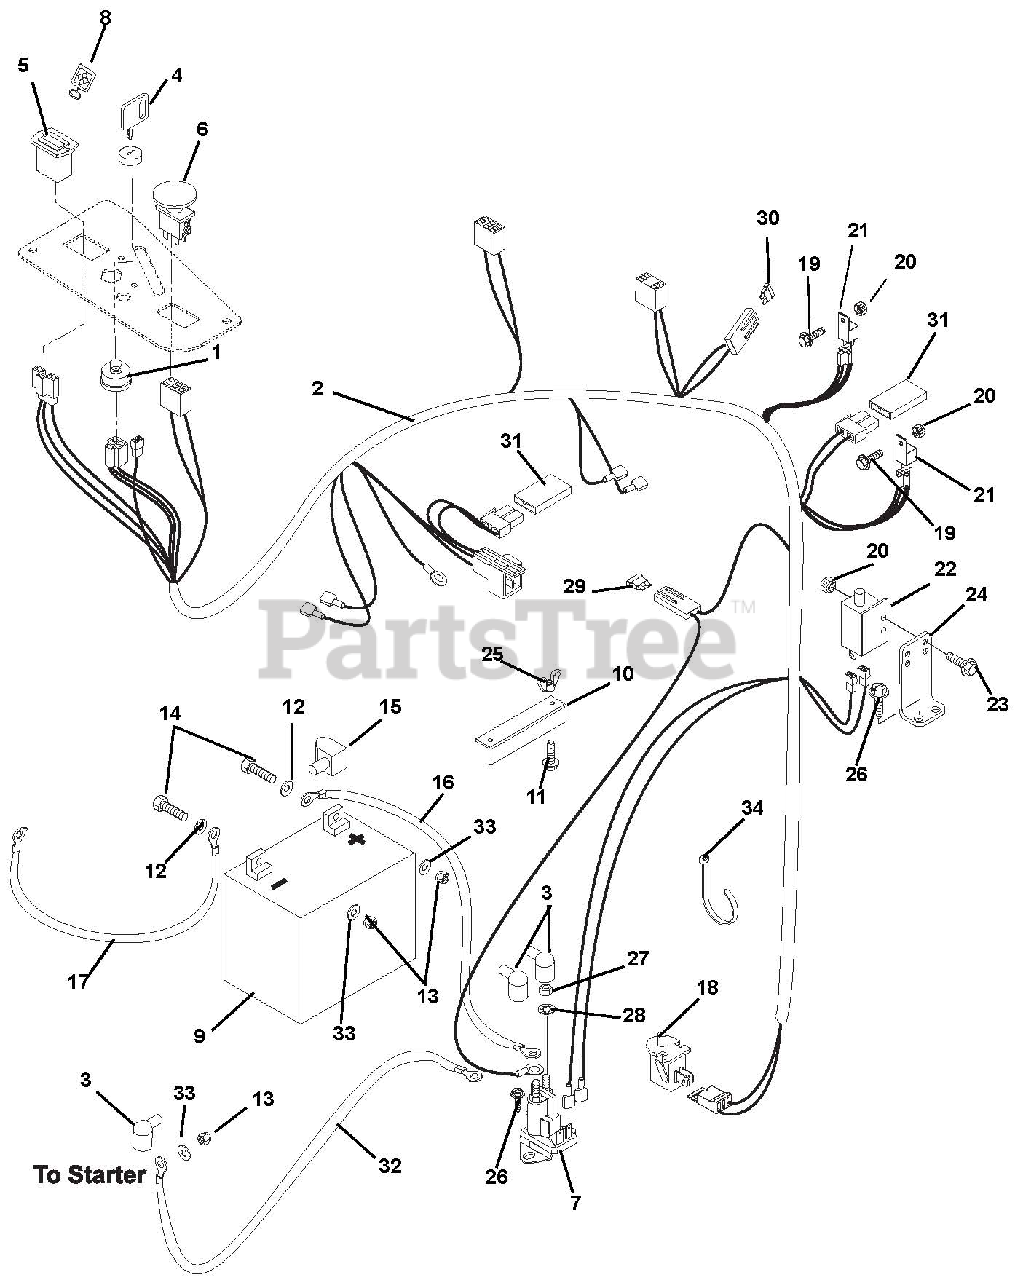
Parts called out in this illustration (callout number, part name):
1	Key Switch
2	Harness, Wiring IZ/CZ 6-Pin
3	Boot, Eyelet Terminal
4	Key with Shield
5	Hour Meter – Digital
6	Switch, Clutch With Retainer Ring
7	Solenoid
8	Key Chain
10	Hold Down
11	Bolt, Round Head Square Neck .25-20 x 7.50
12	Washer, Flat Steel .281 x .620 x .065
13	Nut, Hex .25-20
14	Bolt, Hex .25-20 x .75 Grade 5
15	Insulator
16	Cable, Positive Battery 9.00"
17	Cable, Negative Battery
18	Switch, Snap Mounting (N.O.)
19	Screw, Machine 10-24 x .50 Hex Washer Head
20	Nut, Locking Nylon 10-24 With Insert
21	Relay
22	Switch, Single Pole
23	Screw, Machine 10-24 x .75 Hex Washer Head
24	Mount, Brake Switch
25	Nut, Locking Wing .25-20
26	Screw, Tapping .25-20 x .50 Hex Washer Head
27	Nut, Jam .31-24
28	Washer, Locking .31 x .078 Regular
29	Fuse, 25 Amp
30	Fuse, 20 Amp
31	Diode, Connector Shell
32	Cable, Starter
33	Washer, Lock .25 x .062
34	Tie, Cable LG 5.50
